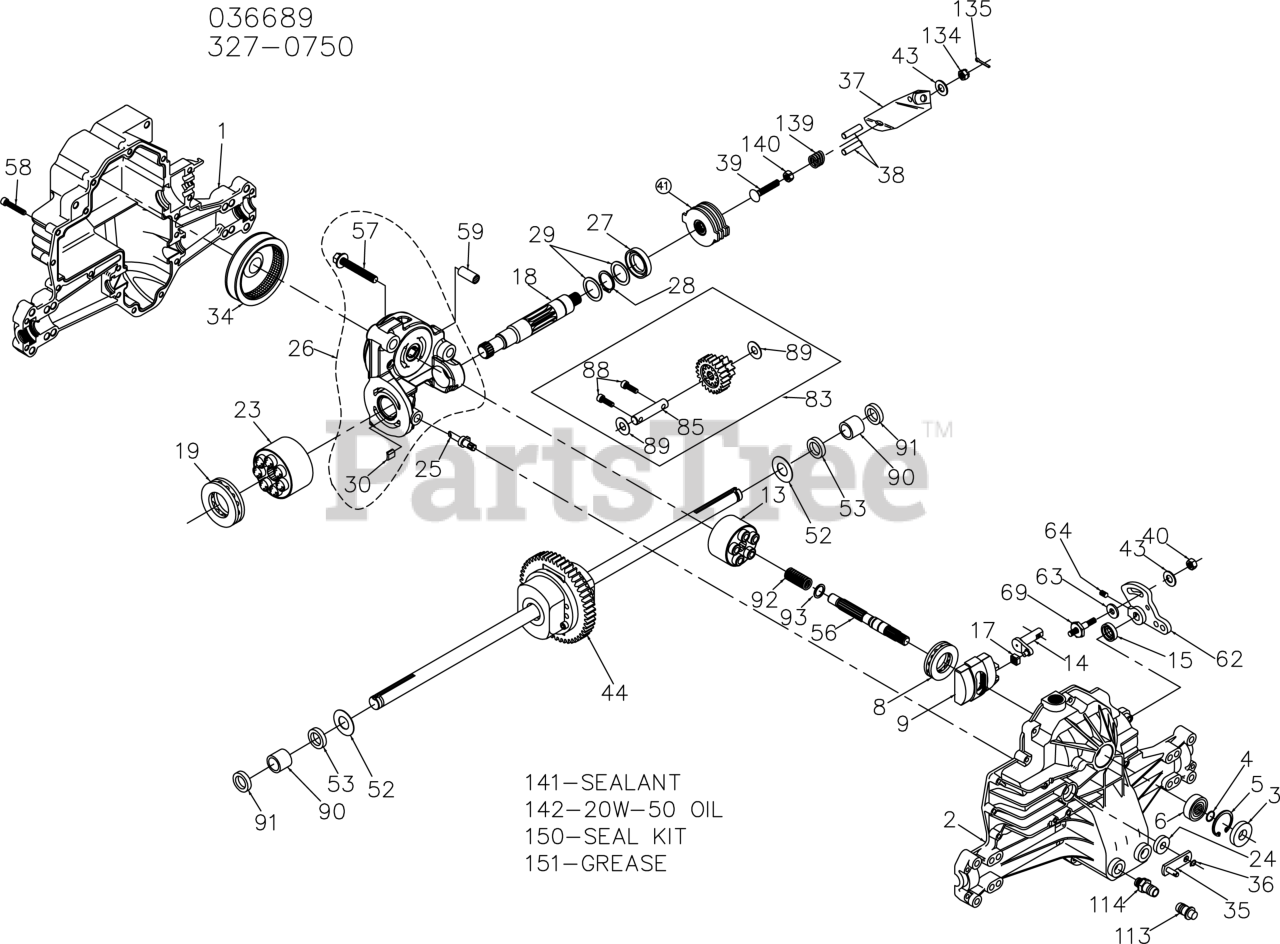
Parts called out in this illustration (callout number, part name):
1	HSG, 0650 LOWER
2	KIT, HSG UPPER
3	SEAL, LIP 15X35X7
4	RING, WIRE RETAINING
5	RING. RETAINING
6	BEARING, SHAFT BALL
8	BEARING. THRUST 30 X 52 X 13
9	SWASHPLATE. VARIABLE
13	KIT, 10 CC BLOCK
14	ARM, TRUNNION 10 CC
15	SEAL, LIP 12X25X7
17	GUIDE. SLOT
18	SHAFT, MOTOR 1O T
19	BRG, THRUST BALL 42X68X16
23	ASSEMBLY BLOCK
24	SEAL, LIP
25	ACTUATOR, BYPASS
26	KIT, C-SECTION
27	SEAL, LIP 26X42X8
28	RETAINING RING
29	WASHER 1.0X1.37X.04
30	KIT, BYPASS PLATE
35	ARM. BYPASS
36	RING, RETAINING
37	ARM, BRAKE
38	PIN, BRK .3X1.25 PLATED
39	RHCS 5/16-24X2 SQ NECK PT
40	NUT, HEX 5/16-24 NYLON
41	KIT, SRVC BRAKE ROTOR/STA
44	KIT, DIFF
52	WASHER .75X1.5X.03
53	SEAL, LIP .75X1.25X.25
56	SHAFT, INPUT
57	HFHCS 3/8-24X2.5 (PATCH)
58	THCS-STAP 1/4-20X1.4
59	PIN-HOLLOW .39X.5X1.
62	ARM, CNTRL PM
63	PACK, FRICTION
64	SCREW, SET 5/16-24 60
69	STUD. SHORT 5/16-24
83	KIT, SRVC JACK SHAFT/PINN
85	SHAFT, JACK
88	SHCS M6X20 (PATCH)
89	WASHER .5X1.0X.032
90	BUSHING .75X1.0X.84
91	SEAL, LIP .75X1X.158
92	SPRING. BLOCK
93	WASHER. THRUST .59 X .79 X .04
113	CAP-VENT .50
114	FTG-STR .50 O-RING
140	NUT, HEX 5/16-24
141	SEALANT TUBE 10.1OZ.
142	FLUID, HYDRO 20W50 QT
142	FLUID, HYDRO 15W50 QT
150	KIT, SEAL
151	GREASE TUBE
